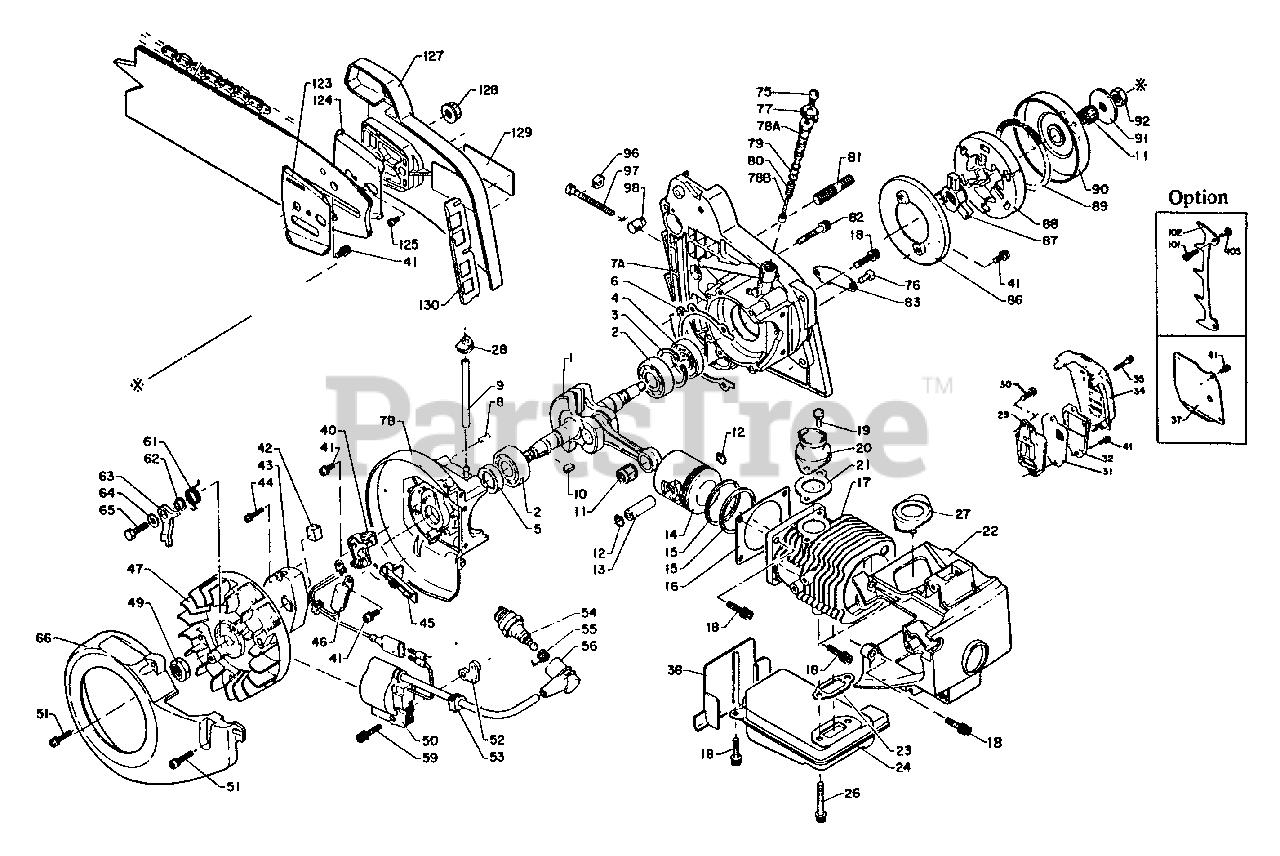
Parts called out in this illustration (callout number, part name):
1	CRANKSHAFT ASSY
2	BEARING, BALL - 6202
3	RING, RETAINING - 35
4	SEAL, OIL
5	SEAL, OIL
6	GASKET, CRANKCASE
7	CRANKCASE KIT
7A	CRANKCASE KIT
7B	CRANKCASE KIT
8	PIN - LOCATING
9	PIPE - 3X6X75 -- BLACK
11	BEARING, NEEDLE
12	RING, RETAINING - 8
13	PIN, PISTON
14	PISTON
15	RING, PISTON
16	GASKET, CYLINDER
17	CYLINDER
18	SCREW - 5X20
19	SCREW - 5X10
20	ADAPTOR, INTAKE
21	GASKET, INTAKE
22	COVER, ENGINE
23	GASKET, EXHAUST
24	MUFFLER
26	SCREW - 5X35
29	ADAPTOR
30	SCREW - 5X14
31	SCREEN, SPARK ARRESTOR
32	RETAINER, SCREEN
34	COVER, EXHAUST
35	SCREW - 4X25
37	COVER, CYLINDER
38	INSULATOR
40	CONTACT POINT SET
41	SCREW - 4X10
42	SCREW - 4X10
42	PAD, OIL
43	COVER, BREAKER
44	SCREW - 3X18
45	CLAMP
46	CONDENSER
47	FLYWHEEL
50	COIL, IGNITION
51	SCREW - 4X20
52	SPACER
53	BUSHING
54	SPARK PLUG -- BPM-6A
55	TERMINAL, SPARK PLUG CAP
56	CAP, SPARK PLUG
59	SCREW - 4X22
61	SPRING, RETURN
62	SPACER
63	PAWL, STARTER
64	WASHER - 5
65	BOLT - 5X20
66	SHIELD, FAN
75	SCREW
76	SCREW - 5X10
77	LOCKWASHER
78	PUMP KIT
78A	PUMP KIT
78B	PUMP KIT
79	O-RING - 5
81	STUD, GUIDE BAR
82	SCREW - 5X30
83	CATCHER, CHAIN
86	SEAL, DUST
87	HUB, CLUTCH
88	SHOE, CLUTCH
89	SPRING, CLUTCH
90	DRUM, CLUTCH
91	WASHER, CLUTCH
92	LOCKNUT
97	SCREW, TENSIONER
98	TENSIONER, CHAIN
101	SCREW - 5X12
102	SPIKE
103	NUT - 5
123	PLATE, GUIDE - INNER
124	PLATE, GUIDE - OUTER
125	SCREW - 3X6
127	GUARD, SPROCKET
128	NUT - FLANGE
129	LABEL - ECHO
